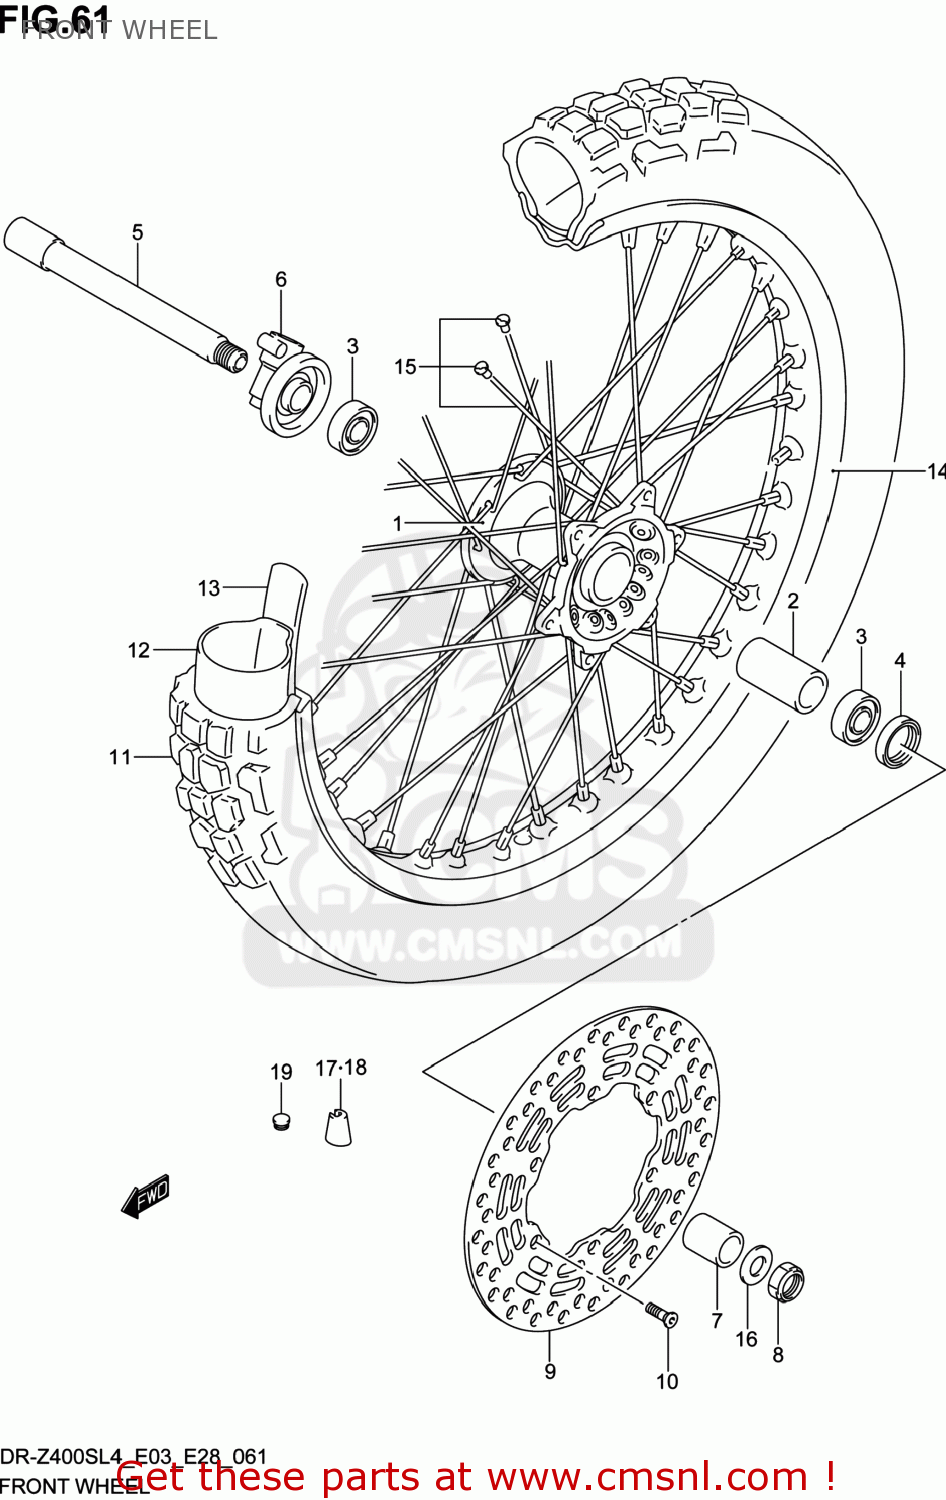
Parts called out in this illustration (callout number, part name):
1	HUB,FR WHEEL
2	SPACER,FR HUB BEARING
3	BEARING
4	SEAL,OIL(25X37X6)
5	AXLE,FR
6	BOX ASSY,SPEEDOMETER GEAR
7	SPACER,FR AXLE,L
8	NUT
9	DISC,FR BRAKE,L
10	SCREW(6X18)
11	TIRE,FR(80/100-21 51P)
12	TUBE ASSY,WHEEL INNER
13	PROTECTOR,WHL INR TUBE
14	RIM,FR WHEEL(21X1.60 AL)
15	SPOKE SET,FR WHEEL
16	WASHER(18X26X2.8)
17	BALANCER,WHEEL(20G)
18	BALANCER,WHEEL(30G)
19	CAP(OD:12)
